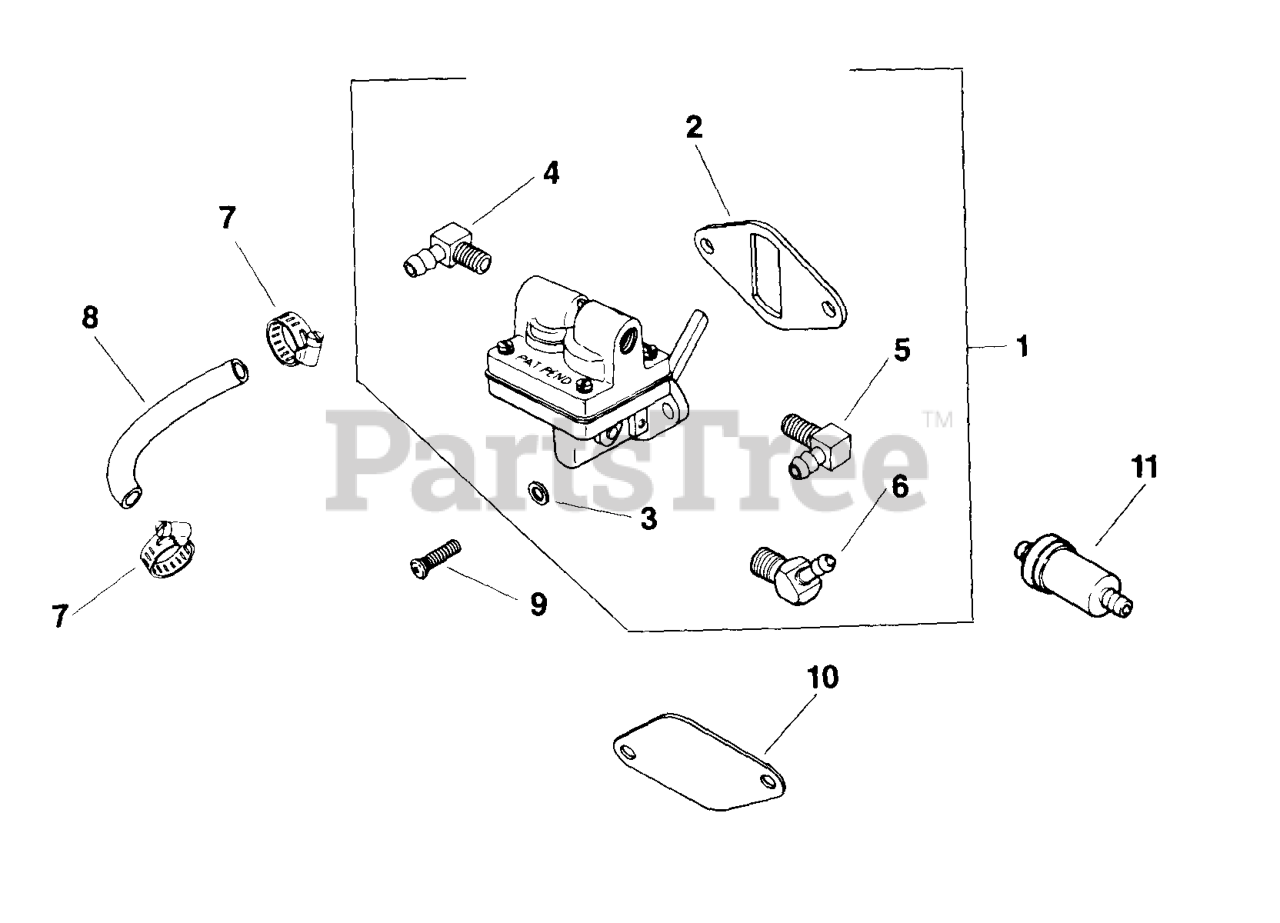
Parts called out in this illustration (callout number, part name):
2	GASKET - USE 25 041 09
3	WASHER, FLAT 1/4" (O.D. 1/2")
4	CONNECTOR, 90 DEG. - DISCONTINUED
5	CONNECTOR, 90 DEG. HOSE
6	CONNECTOR, 45 DEG.
9	SCREW, SEMS 1/4-20X3/4"
